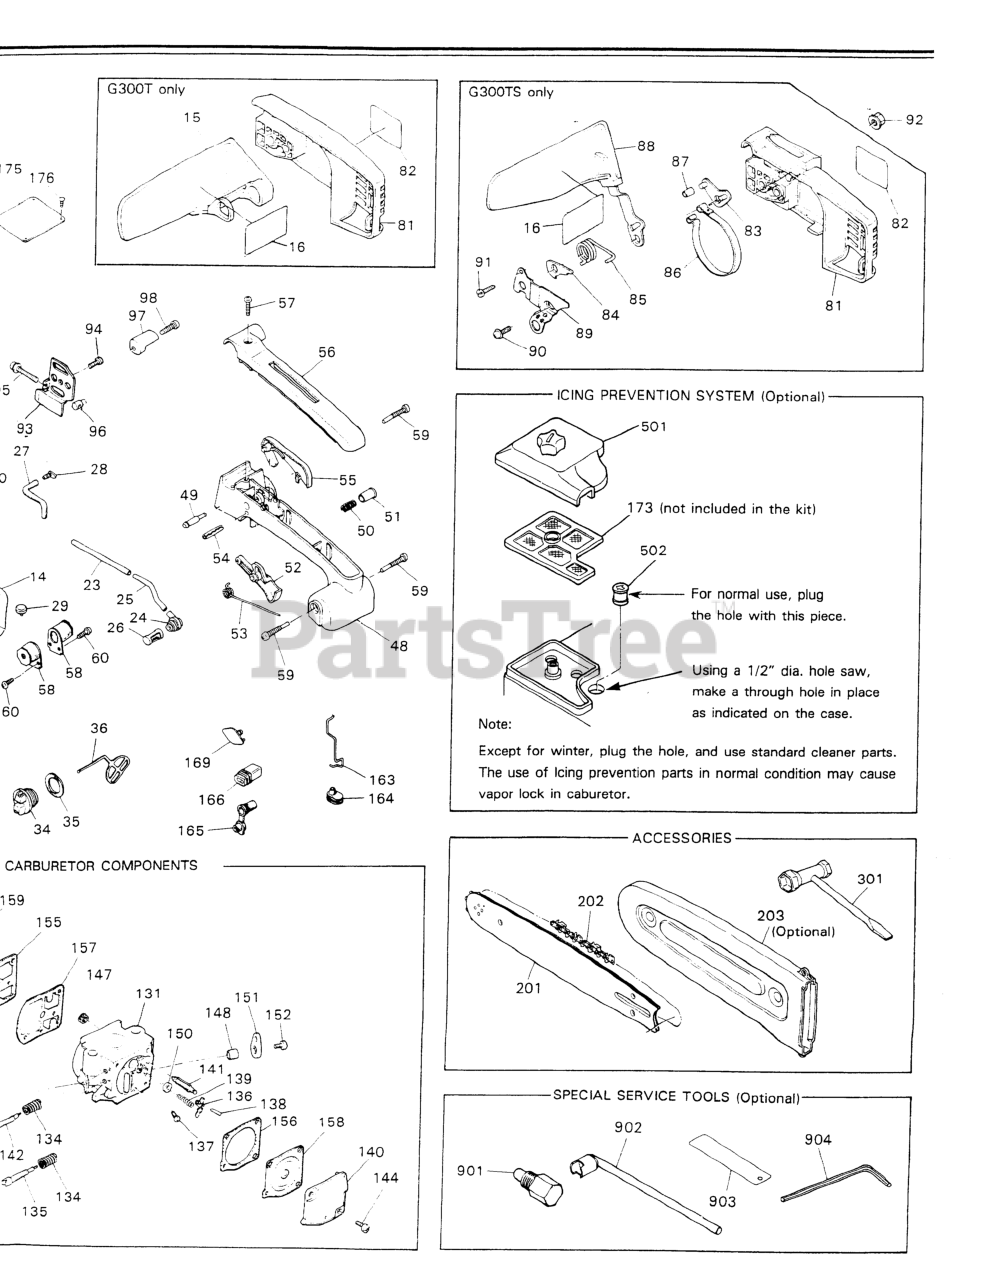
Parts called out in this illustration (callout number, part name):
23	PIPE (USE -85411)
24	GROMMET (RPLS -31320)
27	PIPE (USE -85411)
28	PIN
29	VALVE A
35	GASKET
49	STOPPER
51	KNOB
53	SPRING
57	SCREW
60	SCREW (REPLACES 50030272)
83	ARM ASSY
84	ARM (B) (RPLS -96221)
86	BAND
94	SCREW
96	NUT
97	CATCHER, CHAIN (USE -53412)
134	SPRING (NLA)
137	SCREW (NLA)
141	VALVE (NLA)
144	SCREW (USE -81351)
147	STRAINER (NLA)
155	KIT, GASKET
156	KIT, GASKET
158	KIT, DIAPHRAGM
159	KIT, DIAPHRAGM
163	ROD (USE 2873-82151)
164	GROMMET
165	GROMMET A
169	CAP
175	LABEL, WARNING
201	BAR 14
203	PROTECTOR (14.5
301	WRENCH, PLUG
902	WRENCH (TOOL)
903	GAUGE (TOOL)
904	WRENCH (TOOL)
NI	MUFFLER ASSEMBLY
NI	PIPE COMP (USE -31202)
NI	PIPE ASSEMBLY
NI	ICING KIT
